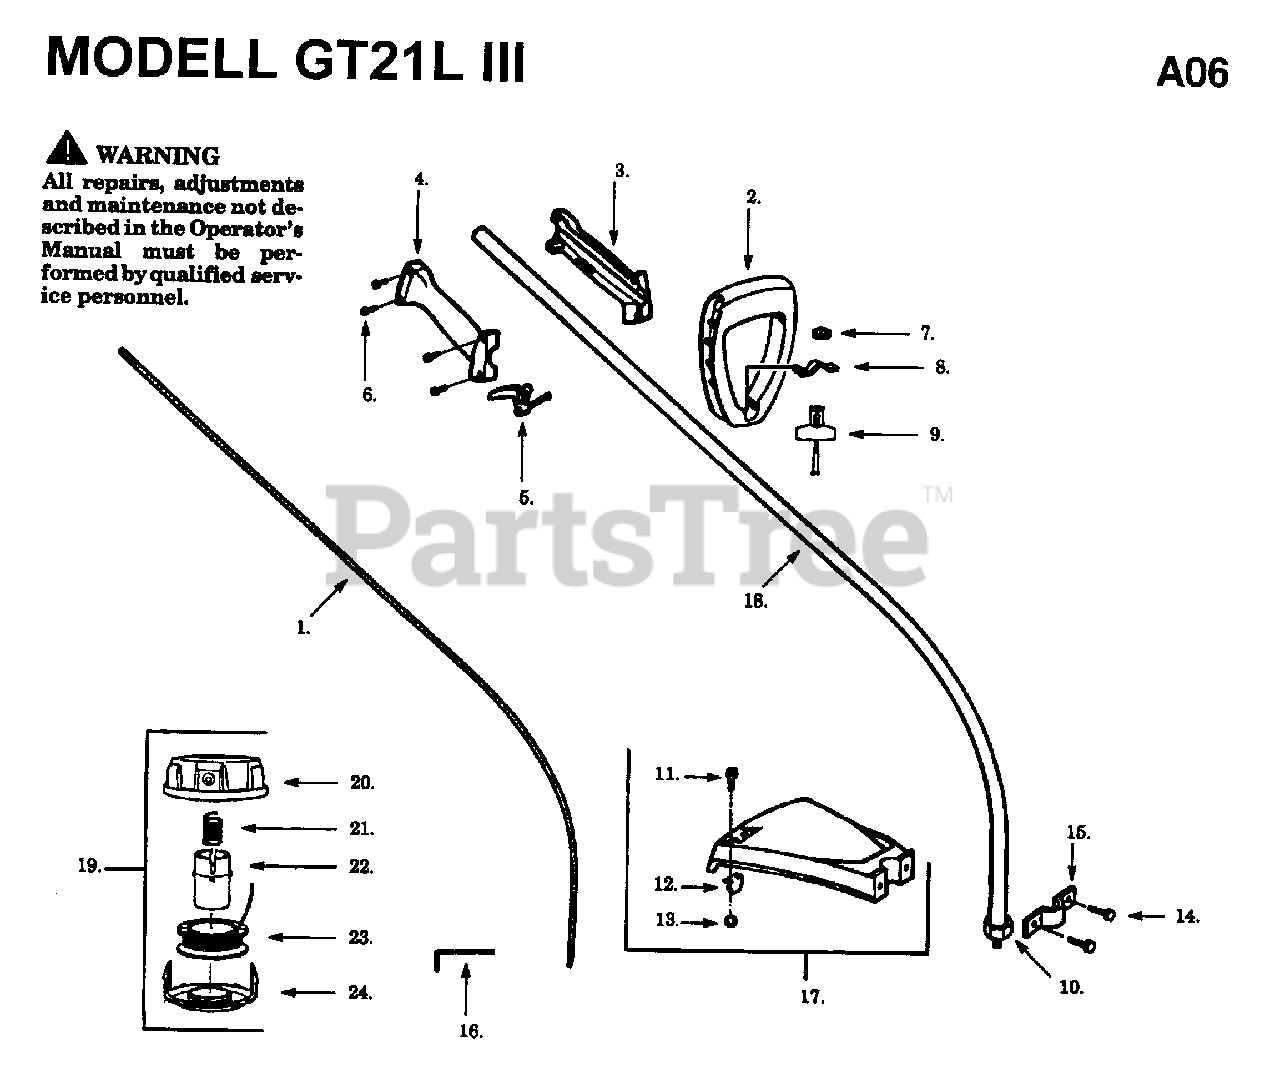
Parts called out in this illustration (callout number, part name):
1	SHAFT-FLEX (48")
2	REPL BY 530 06 94-96
3	THROTTLE HOUSING LEFT
4	THROTTLE HOUSING RIGHT
5	THROTTLE LEVER
6	SCREW - THROTTLE HOUSING
7	NUT (1/4-20)
8	CLAMP-ASSIST HANDLE
9	KIT "T" HANDLE
12	LIMITER-LINE
13	LOCKNUT-(10-24)
14	SCREW-1/4-10X1-1/8 HEX
15	BRACKET-SHIELD
16	ALLEN KEY
17	KIT-SHIELD (SERVICE) BLACK
18	REPL BY 530 09 48-91
19	CUTTING HEAD ASSEMBLY
20	HUB AND SHAFT ASSY
23	SPOOL W/ LINE NLA
